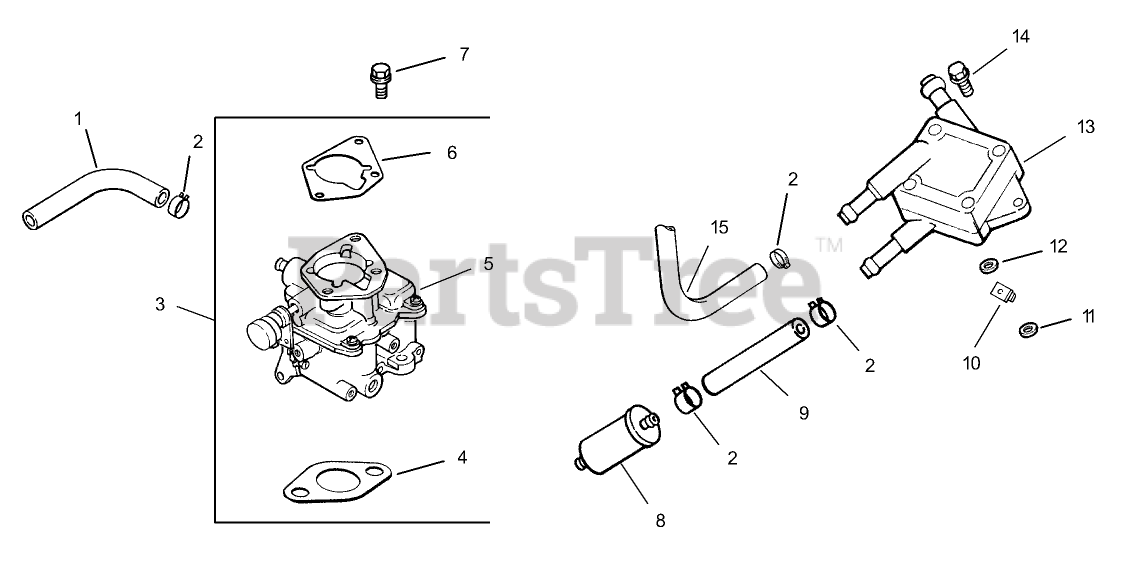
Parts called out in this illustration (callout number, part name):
1	Line-Fuel (9.5)
2	CLAMP-HOSE, SPRING (1/2)
3	Kit, carburetor w/gasket (Includes 4-6)
4	GASKET-BASE, AIR CLEANER
5	Carburetor assembly (For information only not available seperately)(Includes 24 757 01-S, 24 757 02-S, 24 757 03-S, & 24 757 07-S,
6	Gasket-Carburetor
7	SCREW-FLANGE (M6X1.0X30)
8	Filter-Fuel
9	Line-Fuel
10	Nut-Plastic
10	PUMP-FUEL
11	Spacer
11	Screw
12	Washer-Flat (1/4)
12	Line-Fuel, Flexible (15.5)
